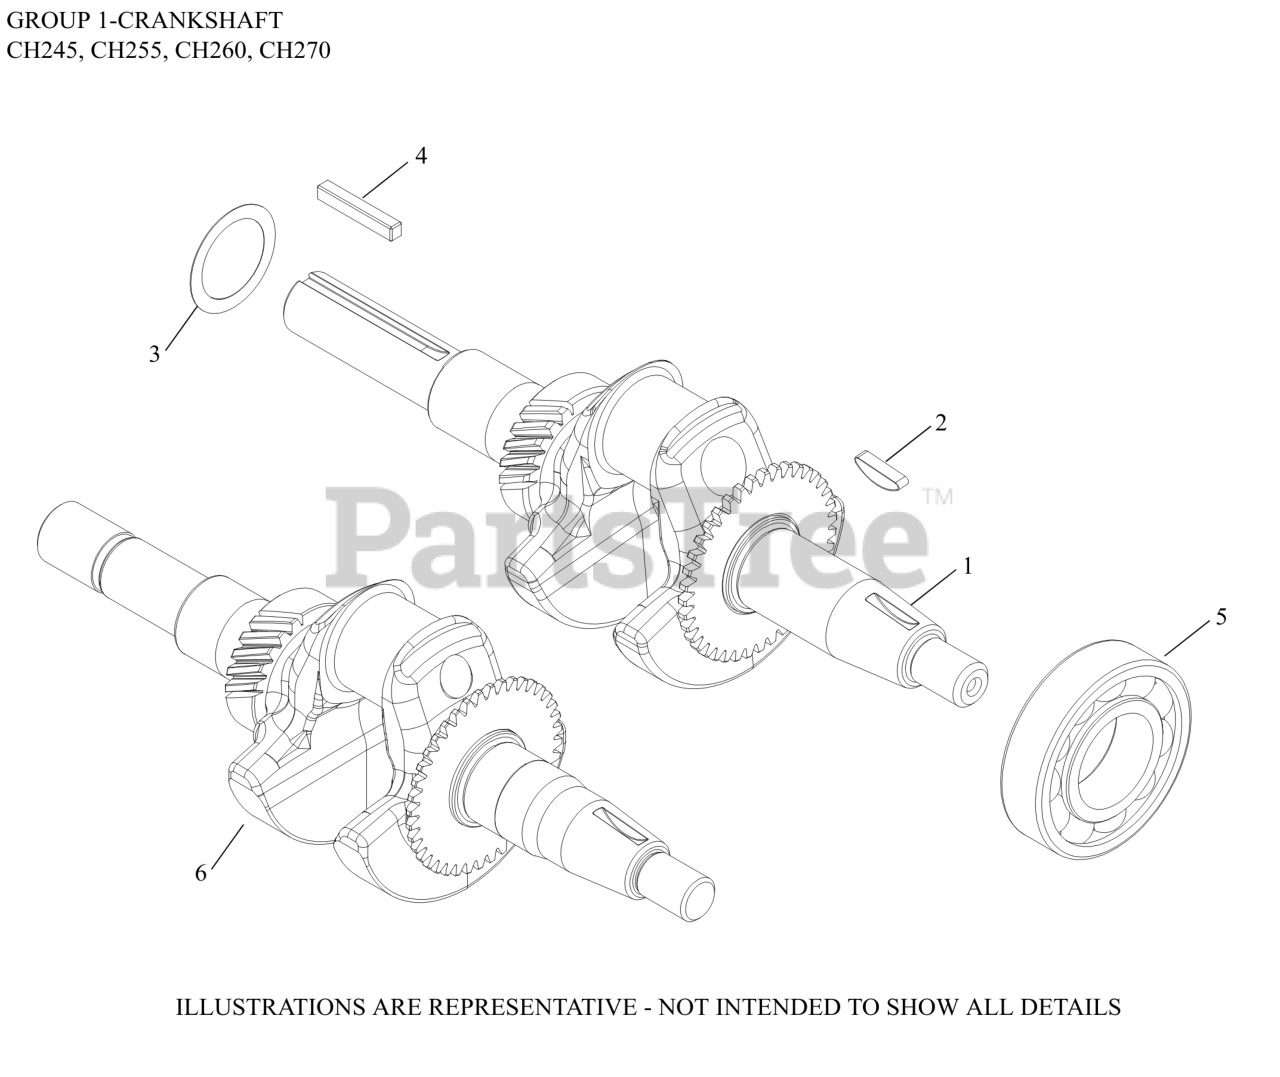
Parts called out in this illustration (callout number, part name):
1	CRANKSHAFT, ASSEMBLY
2	KEY, FLYWHEEL
3	KIT, THRUST SHIM
4	KEY, SQUARE
